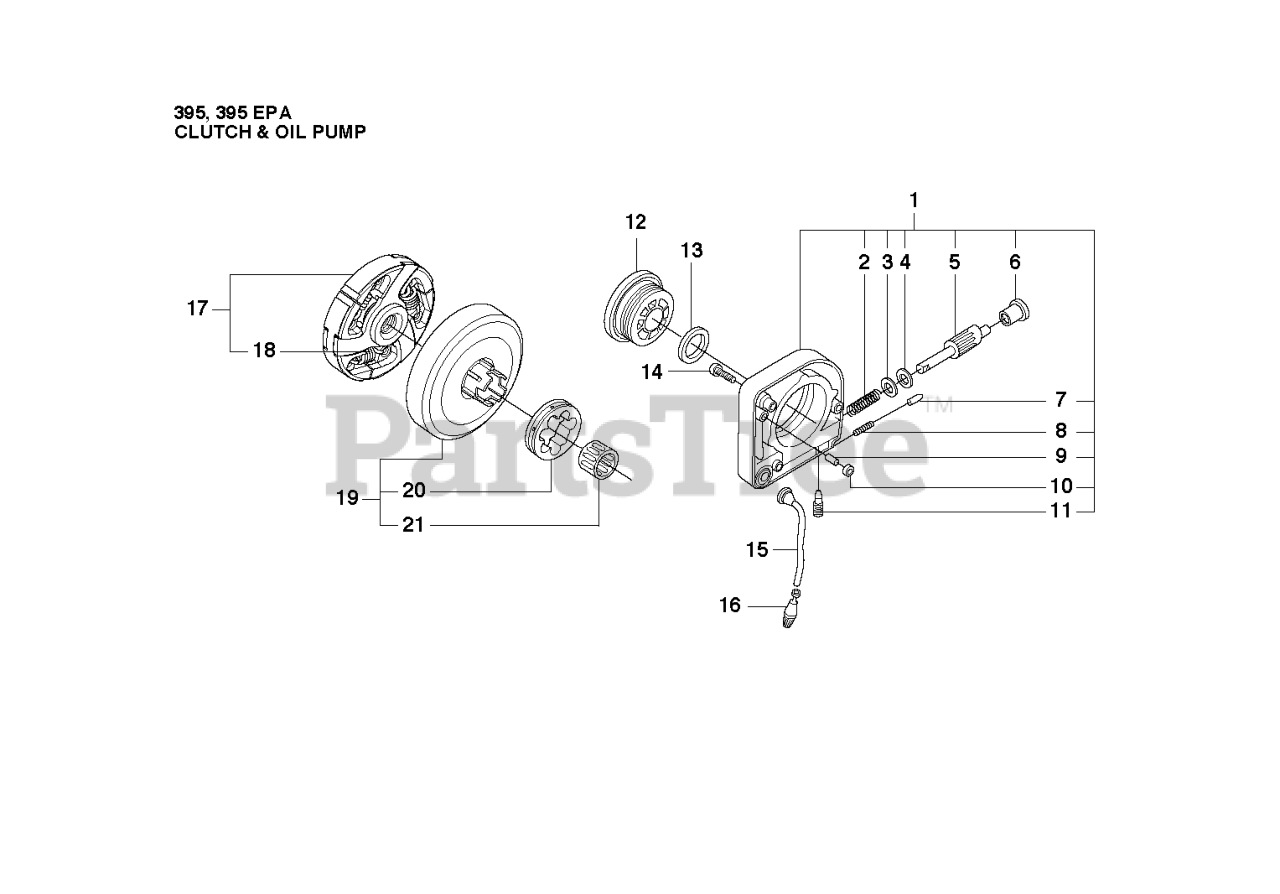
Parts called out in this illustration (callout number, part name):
3	WASHER 6.6X11
4	WASHER 6.6X11
5	PUMP PISTON
9	SPRING PIN 3X6
14	SCREW MC6S 4X20
16	OIL SCREEN
18	CLUTCH SPRING
19	CLUTCH DRUM
20	22270 RIMSPROCKET
20	68210 RIMSPROCKET
21	SUPPORT BUSHING
